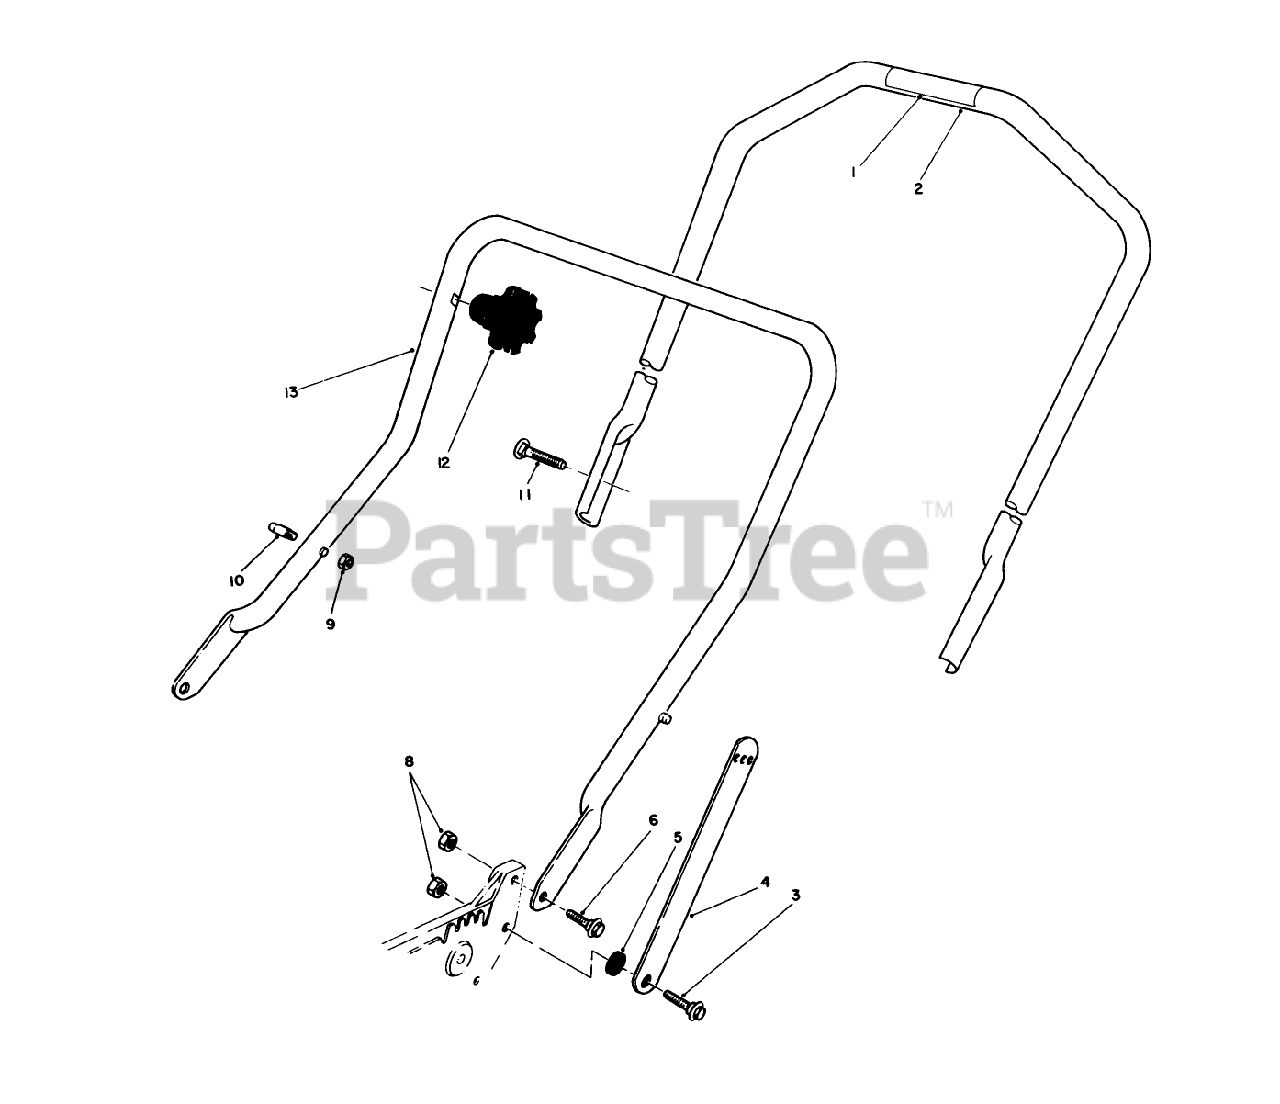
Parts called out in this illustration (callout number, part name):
3	SCREW-SHOULDER
5	SPACER
6	SCREW-SHOULDER
8	NUT-LOCK, NI
9	NUT-LOCK, NI
10	HANDLE PIN
